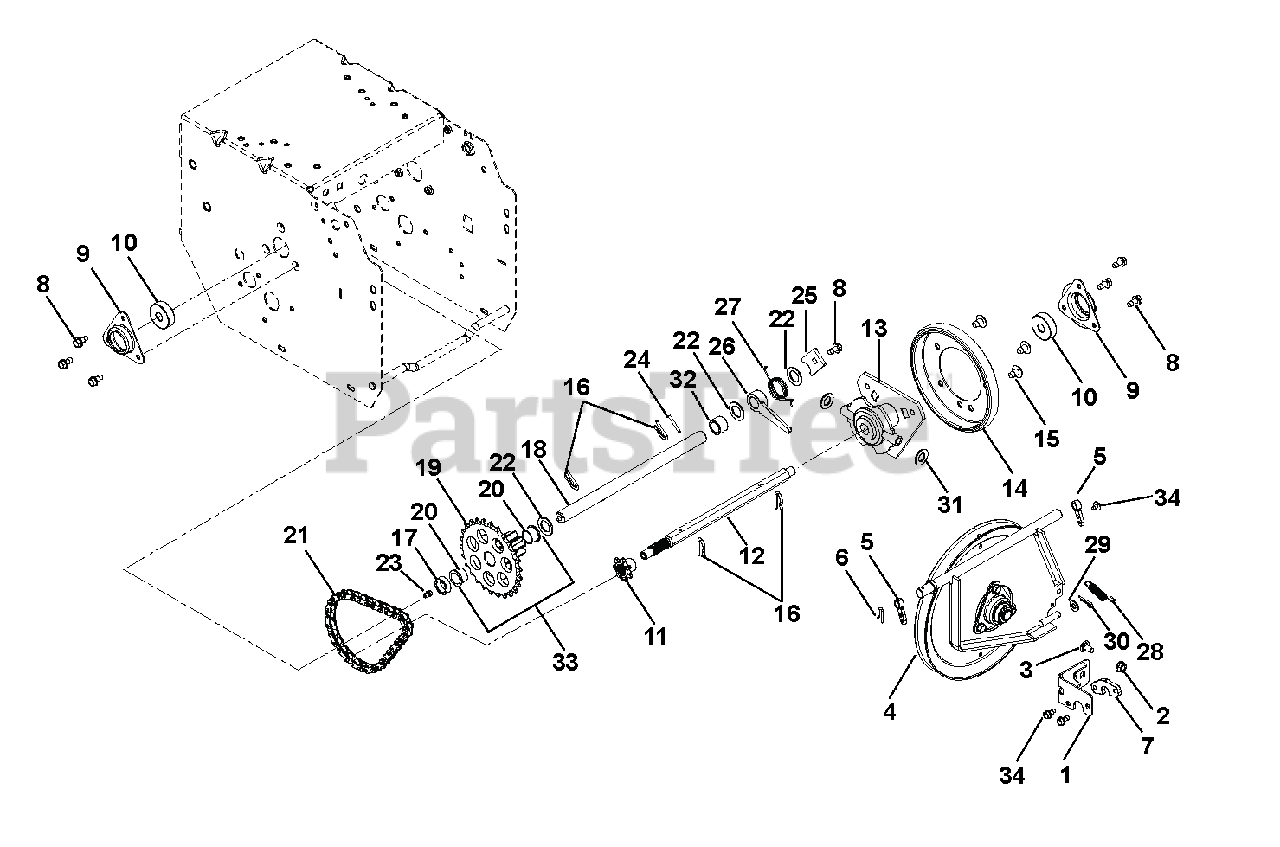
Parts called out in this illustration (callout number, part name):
1	WELDMENT, FRAME BRACKET
2	@NUT-LK-TOP-FLG .31-18 YWZC
3	@BLT-RHDSSQNK .31-18X.62 G5YZ
4	PLATE, SWING - ASSEMBLY
5	SUPPORT BUSHING, SWING GATE
6	CLIP, SPRING
7	SPACER, SWING GATE
8	SCR-TAP .25-20X.50 HWH TR YWZ
9	FLANGE, BEARING
10	BRG-BALL .437X1.375X.437
11	SPROCKET, PINION 7T W/SPLINE
12	SHAFT, HEX W/SPLINE
13	CARRIER, DRIVE DISK
14	FRICTION, DISC
15	SCR-TAP SERRDHDTX .31-18X.50BP
16	PIN, SPRING CLIP
17	BSHG-SLV, .635X.880X.305
18	SHAFT, PINION
19	PINION & SPROCKET
20	BSHG-FLG .625X.750X.500X.875
21	CHAIN - #41, 32 PITCHES
22	WSHR-FL-STL .630X1.005X.062 YZ
23	ZERK,FITTING .25X.125 DRIVE IN
24	@PIN-GRV .125X1.00 TP E ALLOY
25	TAB, ANTI ROTATION
26	LEVER, LOCK ARM
27	SPRING, TORSION
28	SPRING, EXT. .043X.438X1.64
29	@WSHR-FL-STL.344X.688X.065YWZC
30	PIN-HAIR INT .08X.18X1.18 YWZC
31	WSHR-FL-STL .505X1.00X.062YWZC
32	SPACER, .635X.880X.611
33	PINION & SPROCKET W/BUSHINGS
34	SCR-TAP .25-20X.75 HWH TR YWZ
